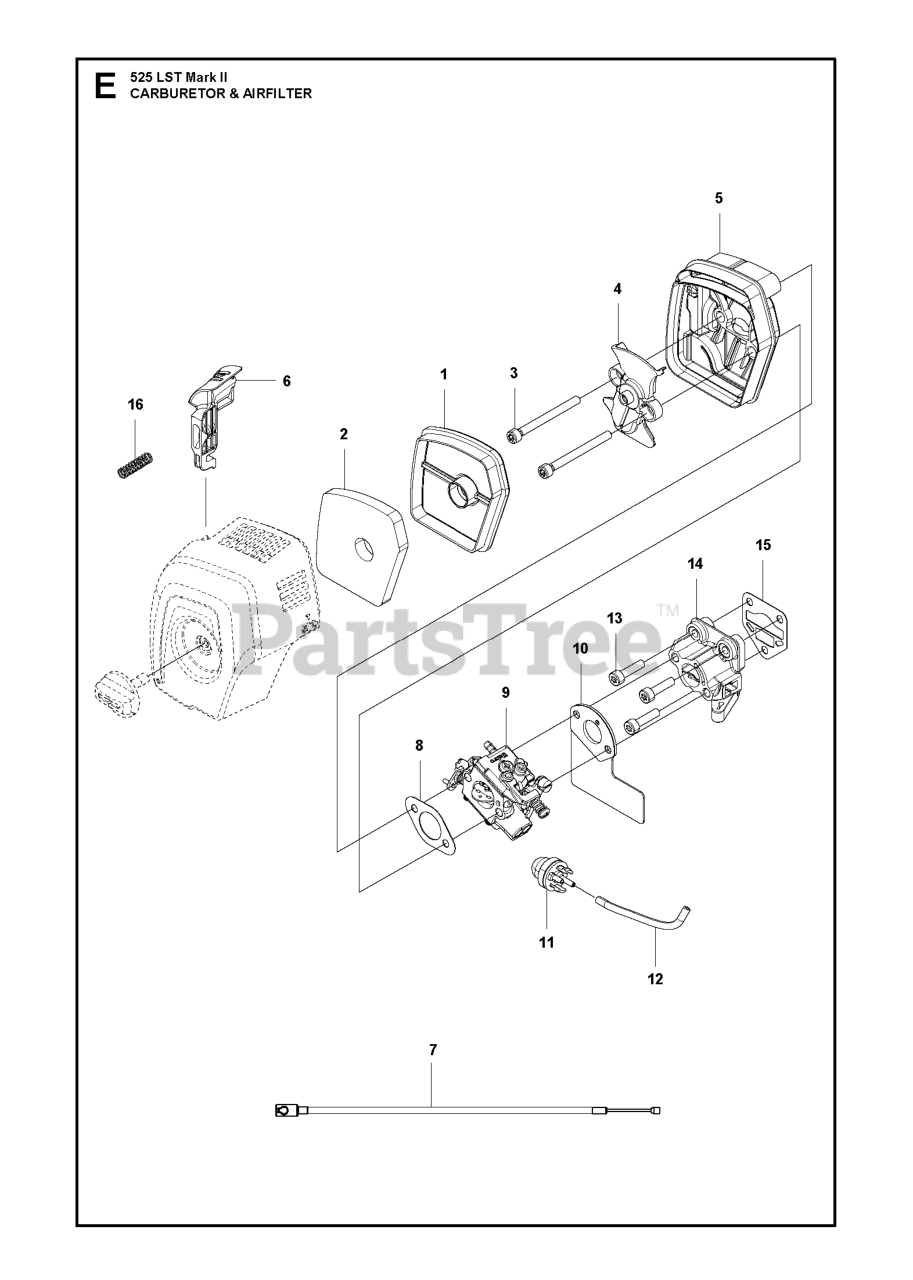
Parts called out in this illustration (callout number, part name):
1	AIR FILTER FELT
2	AIR FILTER URETHANE
4	PLATE BACK SPIT
5	FILTER HOUSING HVA GZ26S
6	CHOKE CONTROL HVA GZ26S
7	THROTTLE CABLE
9	CARBURETOR
10	GASKET CARBURETOR 525 MKII
11	AIR PURGE BUBBLE
13	BOLT
14	INSULATOR HVA GZ26S
16	SPRING CHOKE
